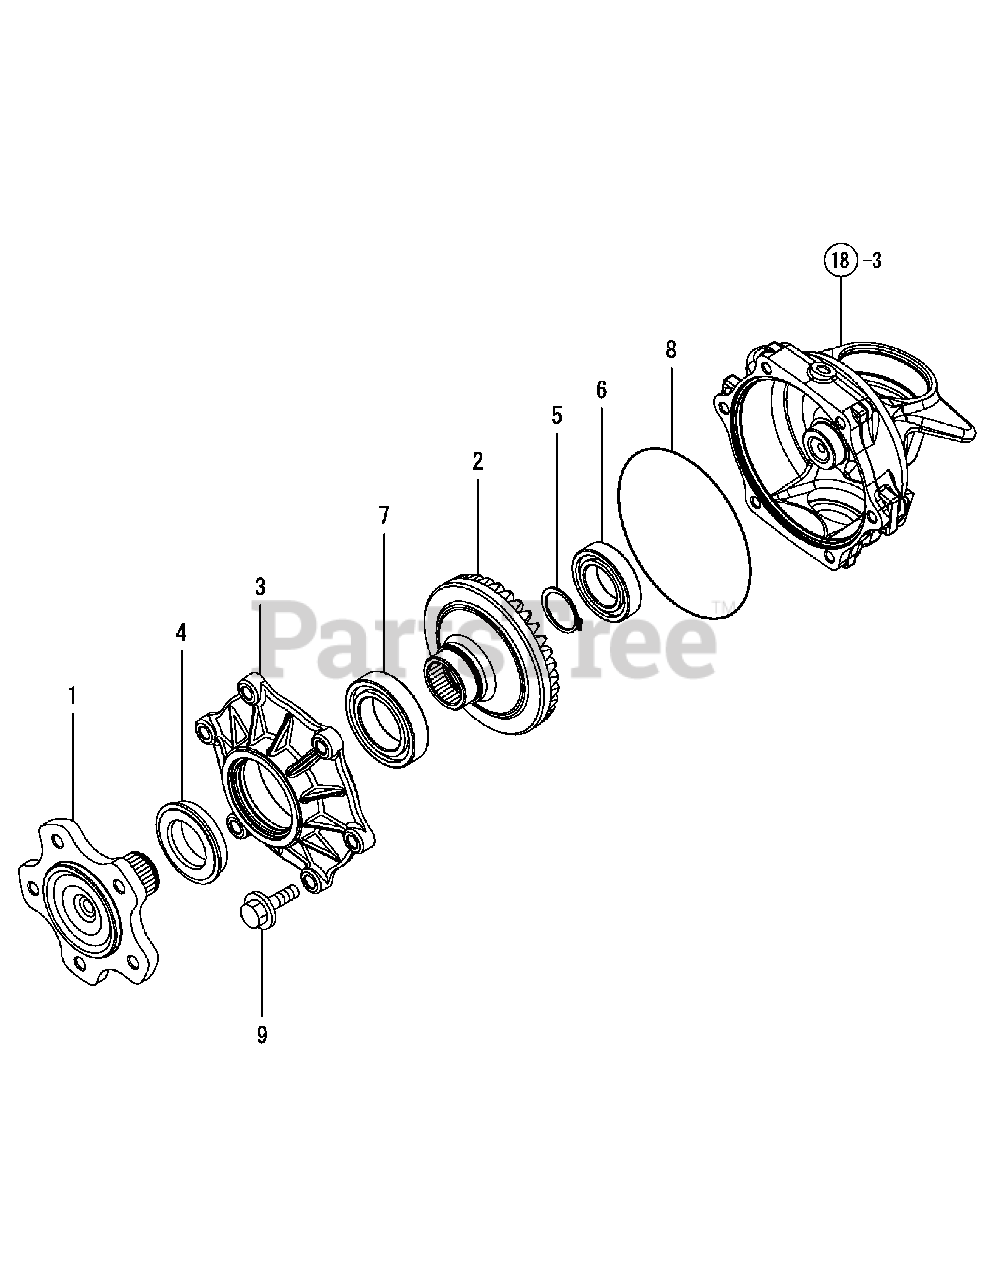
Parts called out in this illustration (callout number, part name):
1	SPINDLE, FRONT
3	CASE,FRONT BEARING
4	SEAL 40X62X14,OIL
8	O-RING 1A G-130.0
9	BOLT M10X 30 PLATED
